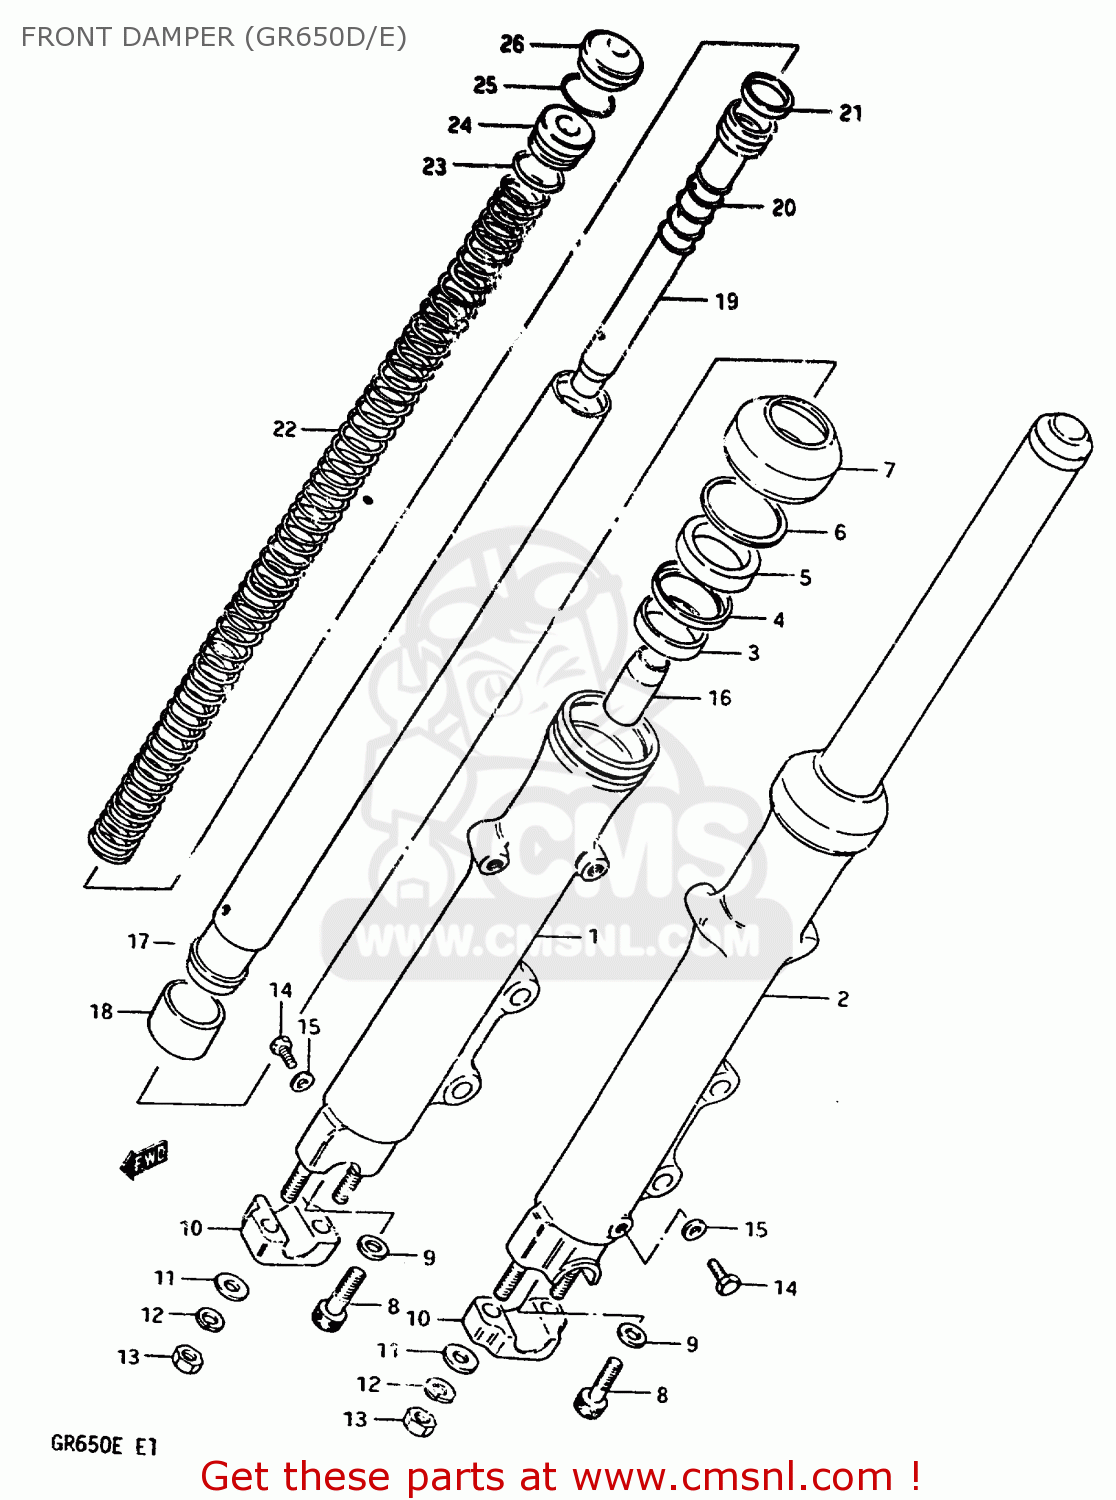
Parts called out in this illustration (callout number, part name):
1	TUBE,OUTER,RIGHT
2	TUBE,OUTER,LEFT
3	BUSHING,GUIDE
4	SPACER,SEAL
5	OIL SEAL,FRONT FORK
6	CIRCLIP,FORK OIL SEAL
7	BOOT
8	BOLT(8X27)
9	GASKET (NAS)
10	HOLDER,AXLE
11	WASHER
12	LOCK WASHER
13	NUT (8MM)
14	BOLT
15	GASKET,DRAIN,PLUG (NAS)
16	PIECE,OIL LOCK
17	TUBE,INNER
18	PISTON
19	CYLINDER
20	SPRING,REBOUND
21	RING,FRONT FORK PISTON
22	SPRING
23	O-RING
24	GUIDE,FRONT FORK SPRING
25	RING,STOPPER
26	CAP
